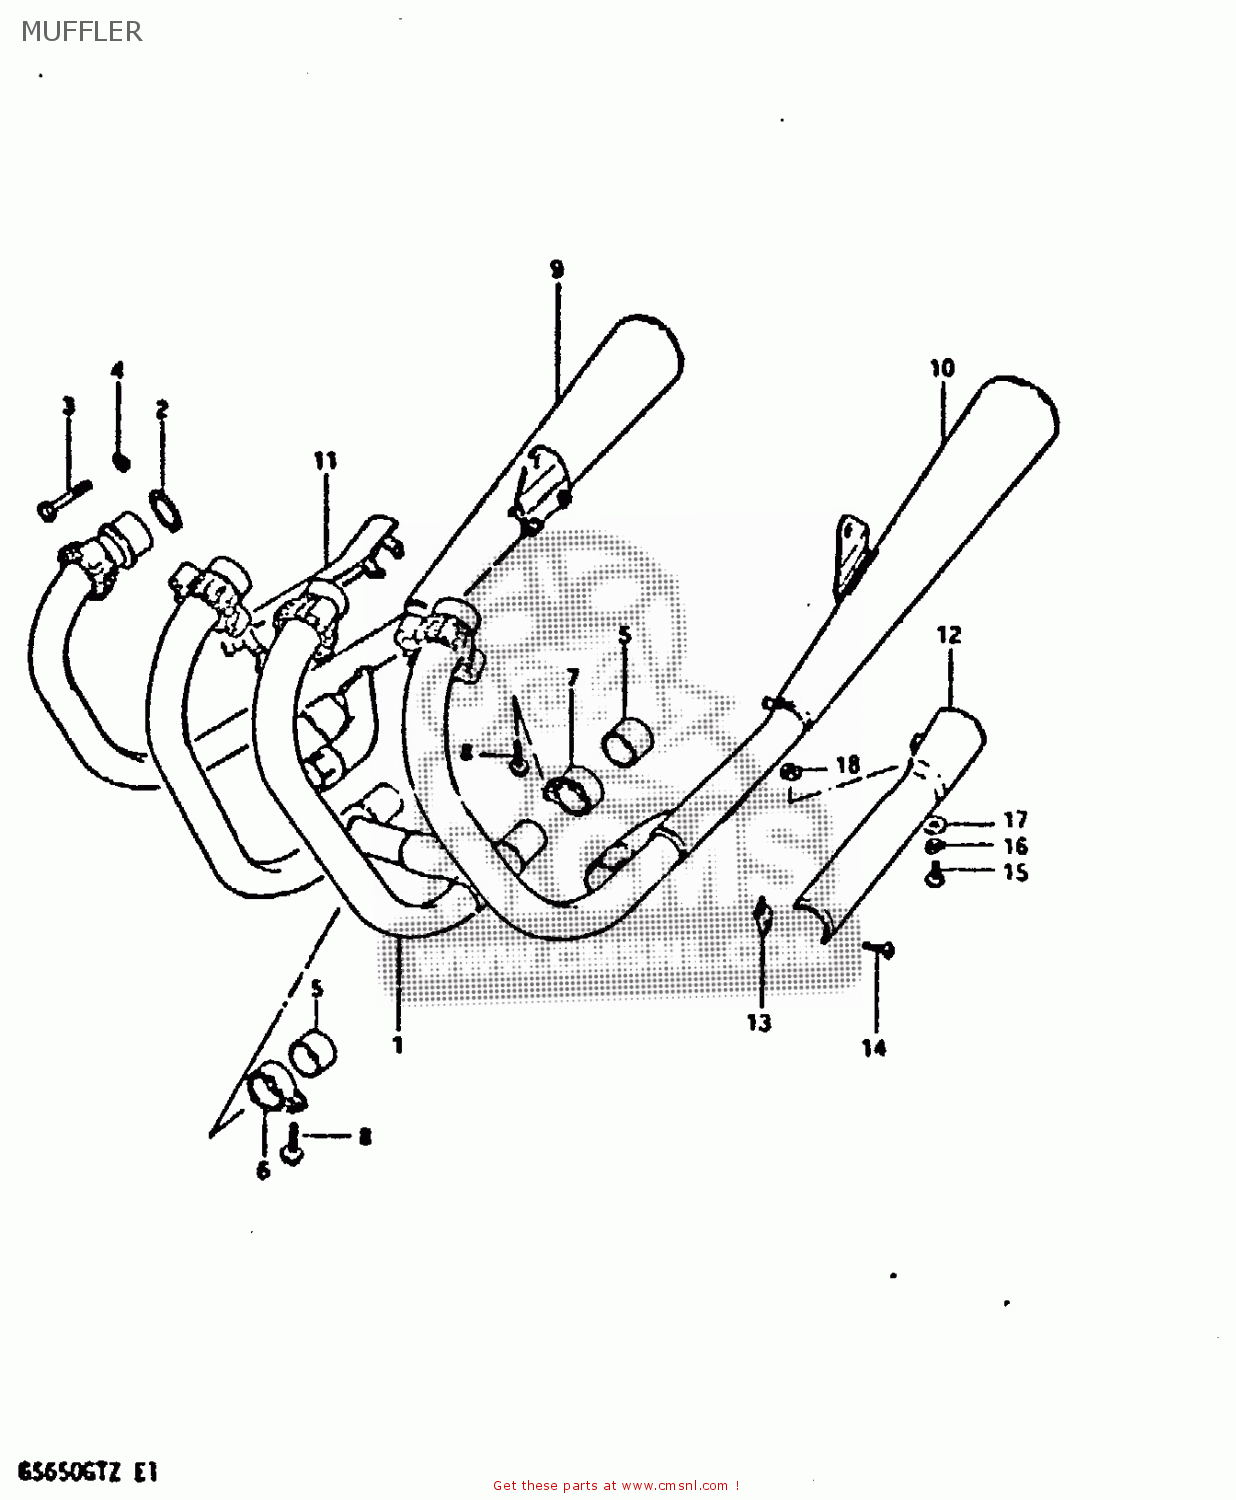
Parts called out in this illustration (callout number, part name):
1	PIPE,EXHAUST CTR
2	GASKET,EXHAUST PIPE (NAS)
3	BOLT 8X40
4	LOCK WASHER
5	CONNECTOR,MUFFLER
6	CLAMP,MUFFLER CONNECTOR,R
7	CLAMP,MUFFLER CONNECTOR,L
8	BOLT
9	MUFFLER ASSEMBLY
10	MUFFLER ASSEMBLY
11	COVER,MUFFLER,RIGHT
12	COVER,MUFFLER,LEFT
13	CLAMP,MUFFLER COVER
14	SCREW 5X20
15	SCREW 6X12
16	LOCK WASHER
17	WASHER
18	GASKET 6.2X12X1.5 (MCA)
